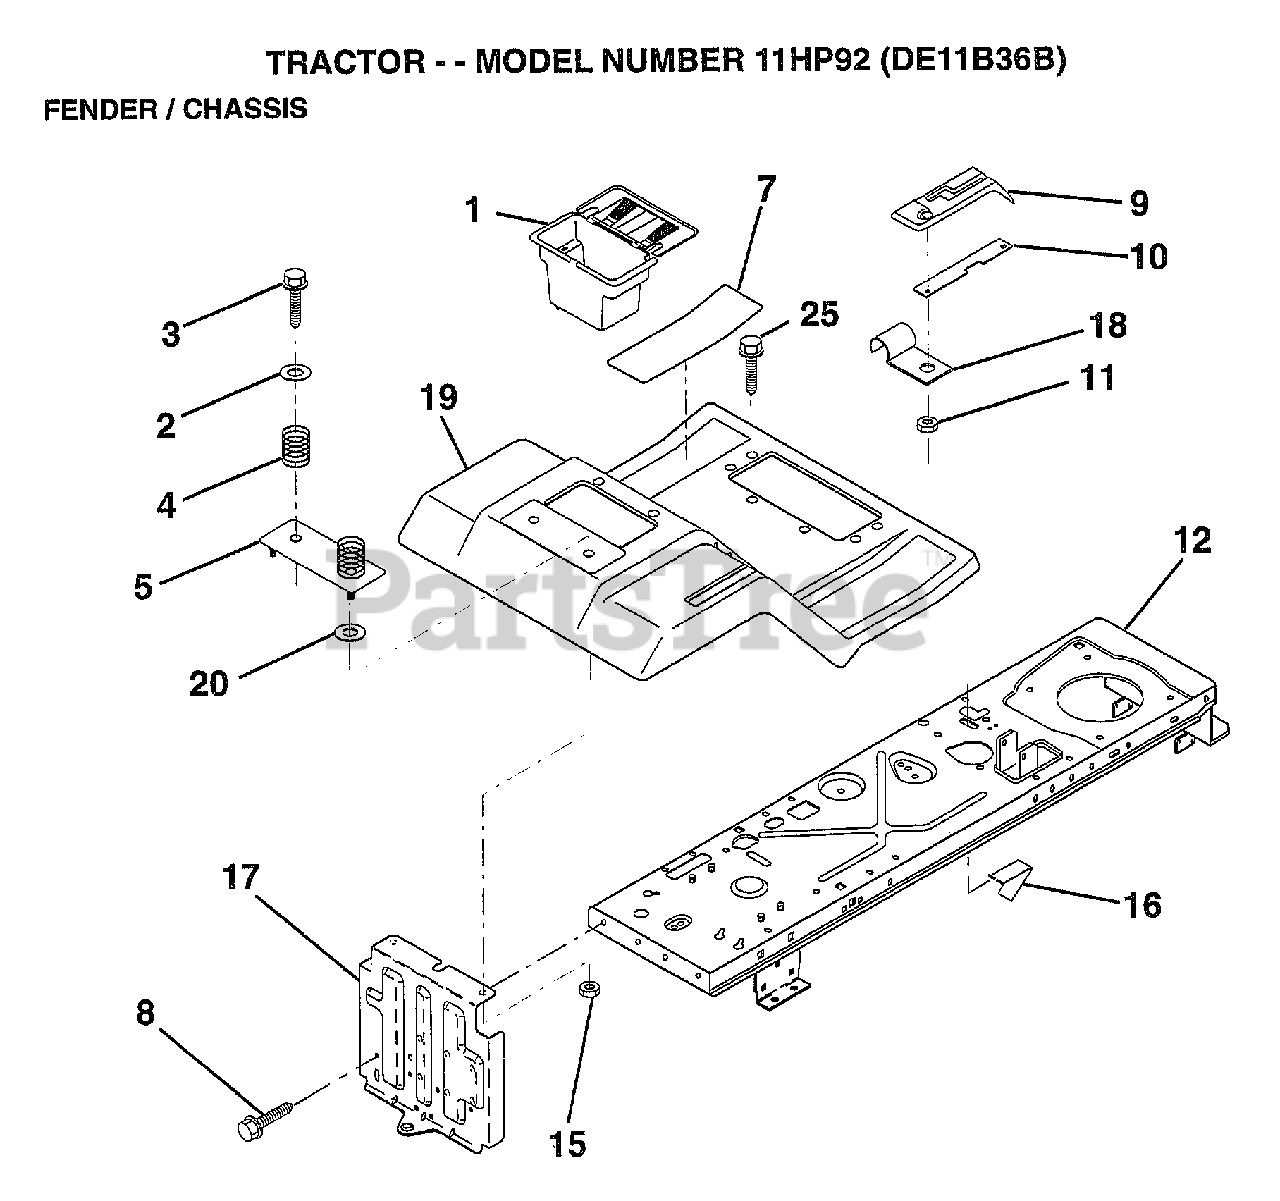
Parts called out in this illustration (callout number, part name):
1	"CASE,BATTERY.MECH"
2	WASHER
3	SCREW
4	SPRING COMPRESSIO
5	PLATE, BATTERY
7	PAD FOOTREST
8	SCREW
9	CONSOLE.SHT.4SP.
10	PLATE LOCK SHIFT
11	NUT
12	CHASSIS.WELD.ASM.
15	NUT HXKEP 1/4X20
17	DRAWBAR ASM LR
18	"CLIP,INSULATOR"
19	FENDER.FOOTREST
25	SCREW TAPPING
